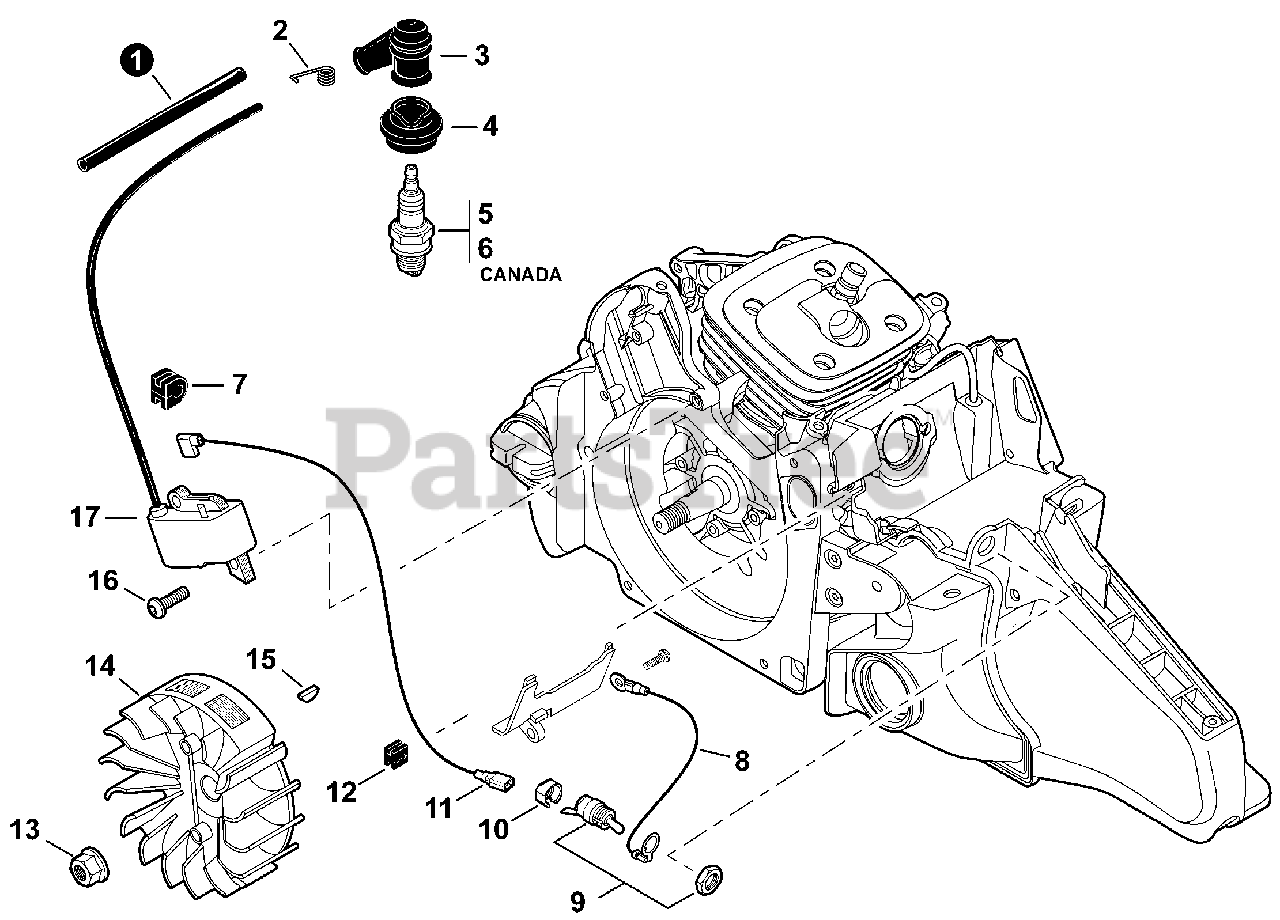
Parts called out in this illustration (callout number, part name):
1	TUBE, IGNITION COIL 6×7.2×70
2	TERMINAL, SPARK PLUG
3	CAP, SPARK PLUG
4	SEAL, SPARK PLUG
5	SPARK PLUG - BPM8Y
6	SPARK PLUG - BPMR8Y
8	LEAD - GROUND L= 170
9	SWITCH, ON-OFF
10	CAP, SWITCH
11	LEAD - IGNITION L= 280
12	GROMMET, LEAD
13	NUT, FLANGE M8
14	FLYWHEEL
15	KEY, WOODRUFF
16	BOLT, TORX 5×16
17	COIL, IGNITION
